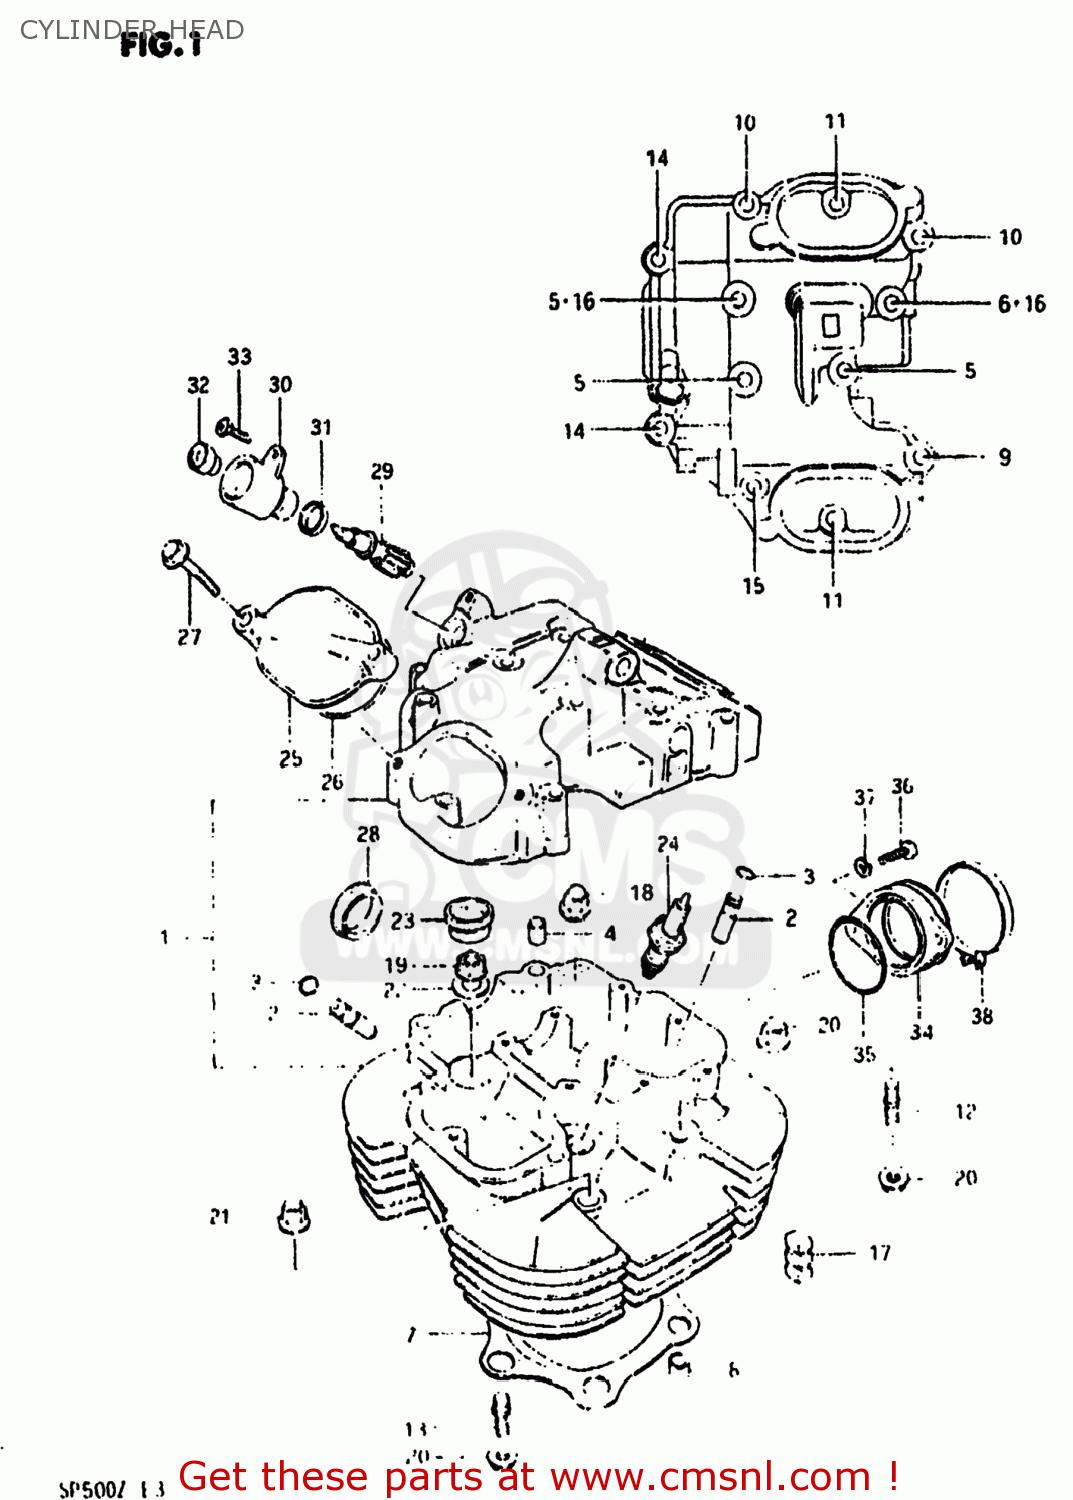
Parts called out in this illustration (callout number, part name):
1	HEAD,CYLINDER (4-VALVE)
2	GUIDE,VALVE
3	RING,SNAP
4	PIN(6.2X8X11)
5	BOLT (6X60)
6	BOLT 6X55
7	GASKET,CYLINDER HEAD (NAS)
8	PIN
9	BOLT ,6X50
10	BOLT,UNDER
11	BOLT
12	STUD
13	STUD
14	BOLT
15	BOLT (6X60)
16	GASKET (NAS)
17	PAD,CYLINDER
18	NUT
19	NUT
20	NUT
21	NUT
22	GASKET (NAS)
23	NUT,CYLINDER HEAD SEAL
24	SPARK PLUG D8EA
25	CAP,INSPECTION HOLE
26	O RING(D:2.4,ID:23)
27	BOLT
28	PLUG(OD:30)
29	GEAR,TACHOMETER DRIVEN
30	SLEEVE,TACHOMETER DRIVE GEAR
31	SEAL,TACHOMETER DRIVEN
32	SEAL,OIL(5X12X8)
33	SCREW(5X12)
34	PIPE,INTAKE
35	O-RING (D:2.4 ID:45.7)
36	SCREW
37	LOCK WASHER
38	CLAMP
